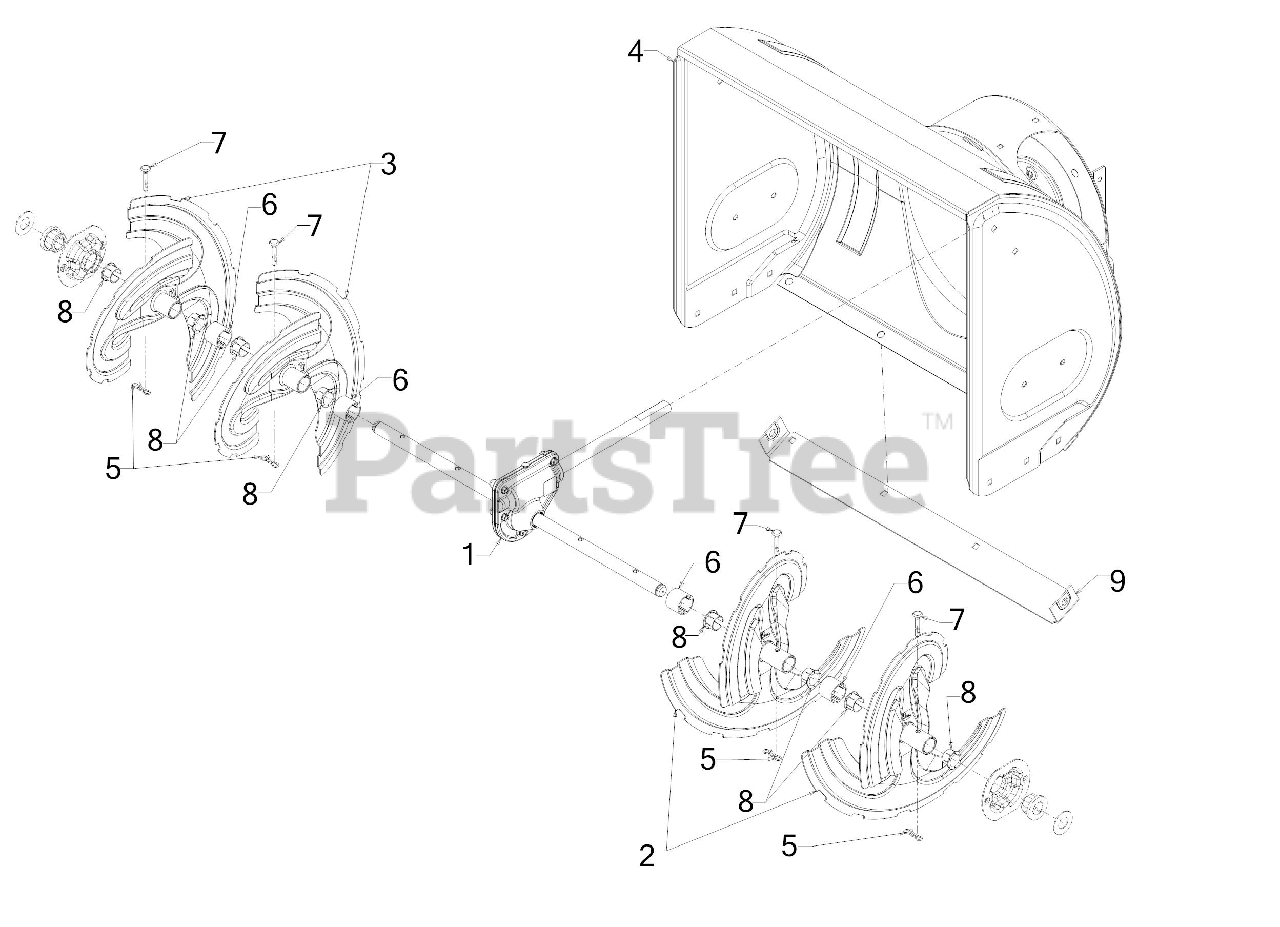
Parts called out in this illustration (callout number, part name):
1	24" GEARBOX ASSEMBLY
5	BOW TIE COTTER PIN 1/4-5/16
6	SPACER 1.25OD x .75ID X1.00 LG
7	SHEAR PIN .25 x 1.50 GR2
8	FLANGE BUSHING
